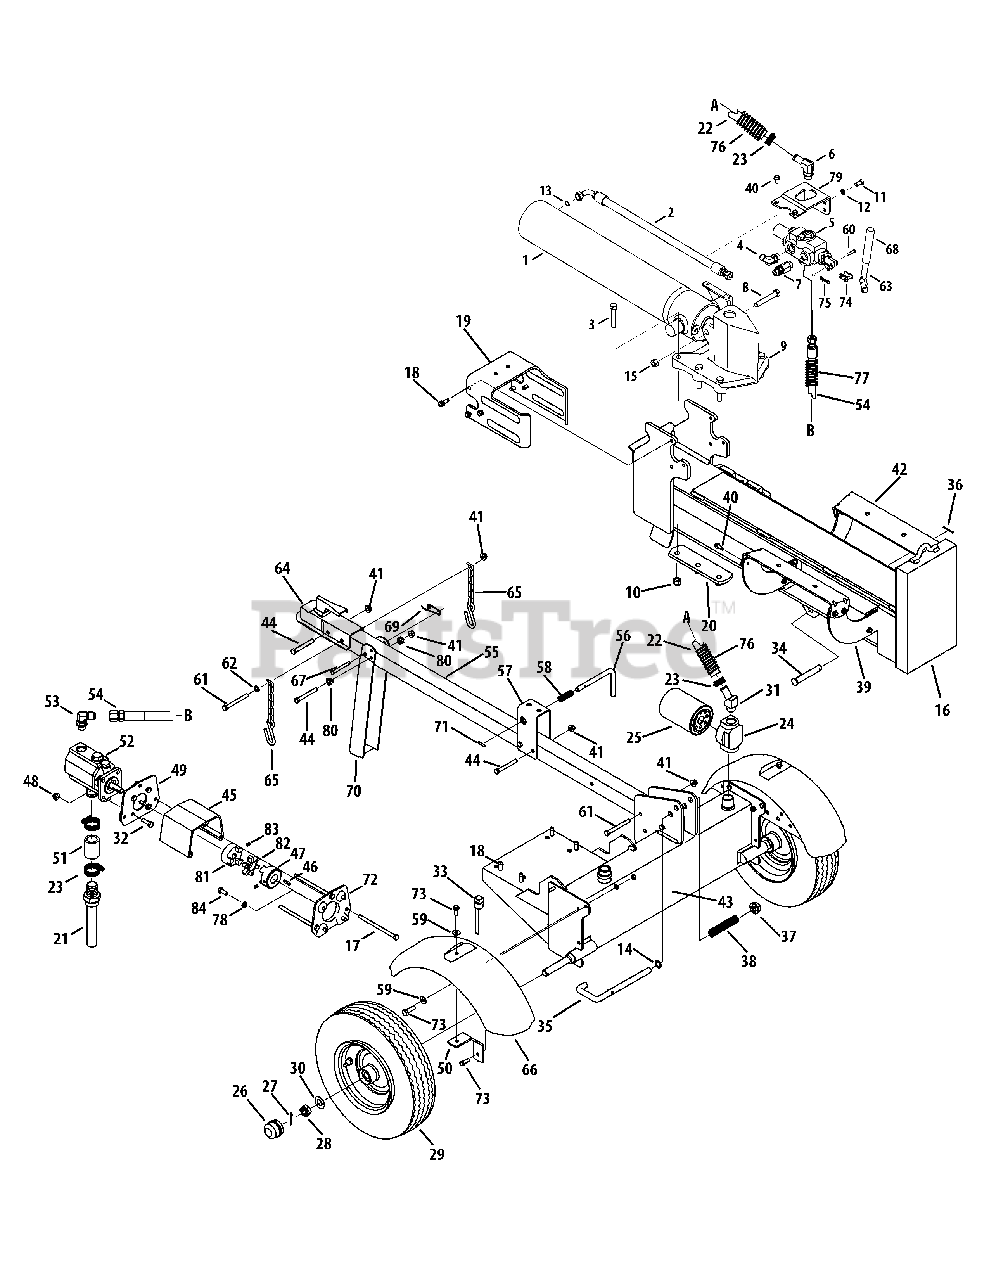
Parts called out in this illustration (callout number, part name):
1	Hydraulic Cylinder
2	Hydraulic Tube
3	Hex Cap Screw, 1/2-20 x 2.75
4	90 Degree Solid Adapter
5	Control Valve
6	Return Elbow
7	Nipple Pipe, 1/2-14
8	Hex Cap Screw, 1/2-13 x 3.25
9	Wedge Assembly
10	Hex Lock Nut, 1/2-20
11	Hex Cap Screw, 3/8-16 x .75
12	Lock Washer, 3/8
13	O-Ring, .489 ID x .070 Dia.
14	Flat Washer, .635 x.93 x.06
15	Hex Lock Nut, 1/2-13
16	Beam Assembly
17	Hex Screw, 5/16-18 x 4.00
18	Self Tapping Screw, 3/8-16 x 1.0
19	Dislodger Bracket
20	Back Plate
21	Inlet Filter
22	Return Hose, 3/4 x 44
23	Hose Clamp, 5/8
24	Filter Housing
25	Oil Filter
26	Hub Cap
27	Cotter Pin
28	Slotted Nut, 3/4-16
29	Complete Wheel Assembly
29	Dust Seal
29	Roller Bearing
30	Flat Washer, .760 x.500
31	Hydraulic Fitting, 1 1/16 Orb x .75
32	Hex Screw, 5/16-18 x 1.00
33	Vented Dipstick
34	Clevis Pin
35	Lock Rod
36	Cotter Pin
37	Push Cap
38	Compression Spring
39	Log Tray Bracket
40	Hex Washer Screw, 5/16-18 x .750
41	Flange Lock Nut, 3/8-16
43	Frame Assembly - MTD Engine
44	Hex Bolt, 3/8-16 x 3
45	Coupling Shield
46	Square Key, 3/16" x .75
47	Coupling, .750
48	Flange Lock Nut, 5/16-18
49	Rear Coupling Support Bracket
50	Fender Mounting Bracket
52	Gear Pump
53	45 Degree Elbow Fitting
54	High Pressure Hydraulic Hose
55	Tongue Assembly
56	Latch Rod
58	Compression Spring
59	Flat Washer
60	Clevis Pin
61	Hex Cap Screw, 3/8-16 x 3.50
62	Flat Washer, .375 x.738 x.063
63	Hydraulic Valve Control
64	Hitch Coupling Assembly
66	Fender
67	Clevis Pin
69	Spring Pin
70	Jack Stand
71	Spiral Pin
72	Front Coupling Support Bracket
73	Self-Tapping Screw, 5/16-18 x 1.00
74	Valve Handle Link
75	Cotter Pin, Bow Tie
76	Hose Guard, 44"
77	Hose Guard, 48"
78	Lock Washer, 5/16
79	Outer Valve Bracket
80	Plastic Bushing, .380 ID
81	Coupling, .500
82	Spider Bushing
83	Set Screws
84	Hex Cap Screw, 5/16-24 x .75
